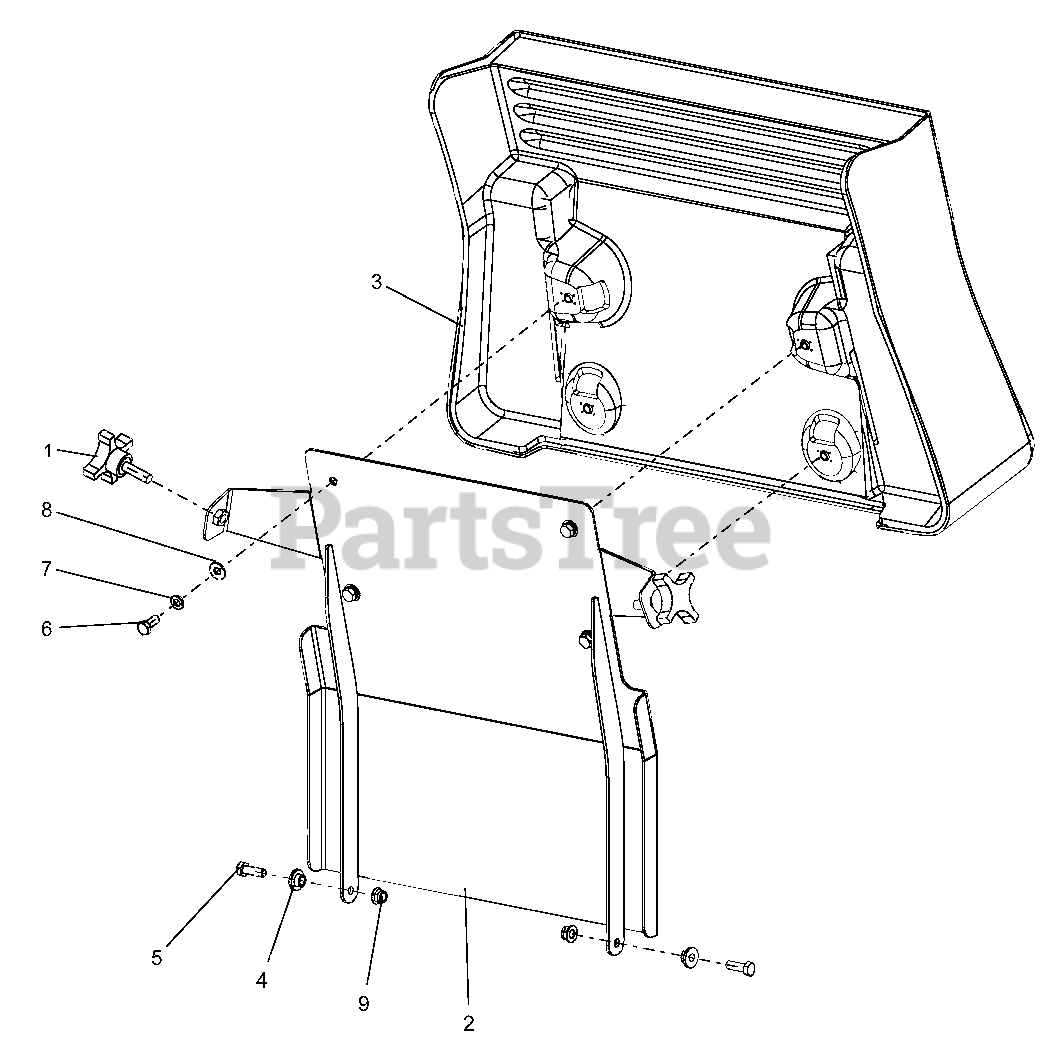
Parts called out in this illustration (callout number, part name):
1	KNOB, 3/8 X 1.25 - 4 PRONG
2	WLDMT, PAD MOUNT
3	PAD, PROSTANCE
4	BSHG-FLG .312 X .500 X .344
5	BLT HEX .31-18 X 1.00 GR5 YWZC
6	BLT HEX .31-18 X .75 GR5 YWZC
7	WSHR-LK .31 X .078 REG YWZC
8	WSHR-FL-STL .312 X .734 X .065 YWZ
9	NUT LK NYL FLG .31-18 YWZC
